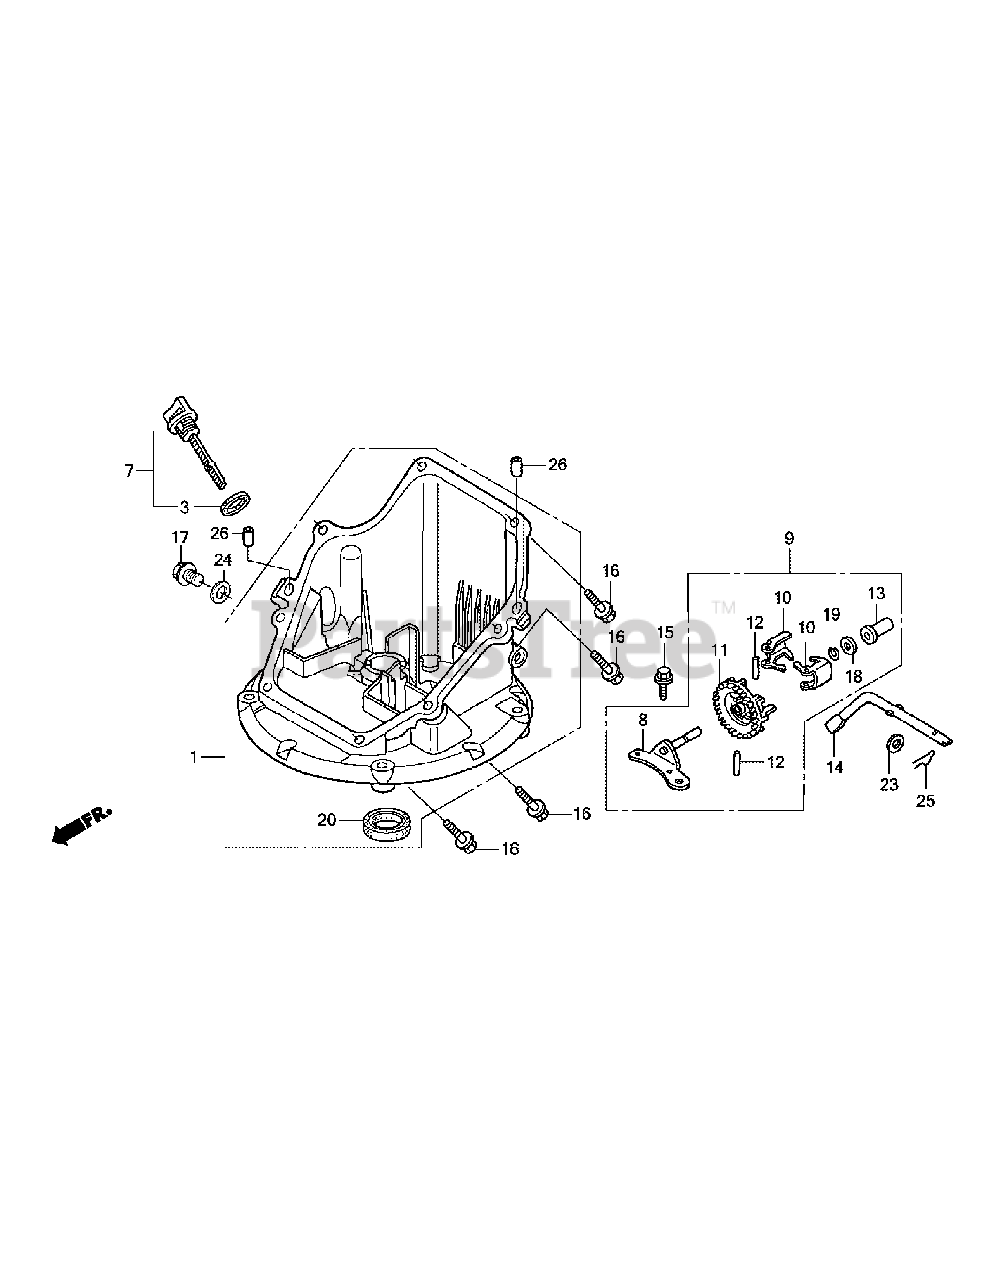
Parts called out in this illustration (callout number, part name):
1	Oil Pan Assembly
3	Oil Filler Cap Gasket
7	Oil Level Gauge Assembly
8	Governor Holder Shaft
9	Governor Assembly
10	Governor Weight
11	Governor Weight Holder
12	Governor Weight Pin
13	Governor Slider
14	Governor Arm Shaft (to 1642935)
14	Governor Arm Shaft (from 1642936)
15	Flange Bolt, 6 x 14
16	Flange Bolt, 6 x 25
17	Drain Plug Bolt
18	Thrust Washer, 6mm
19	Governor Holder Clip
20	Oil Seal, 28 x 41.25 x 6
23	Plain Washer, 6mm
24	Drain Plug Washer, 12mm
25	Lock Pin, 8mm
26	DowelPin,8x20
